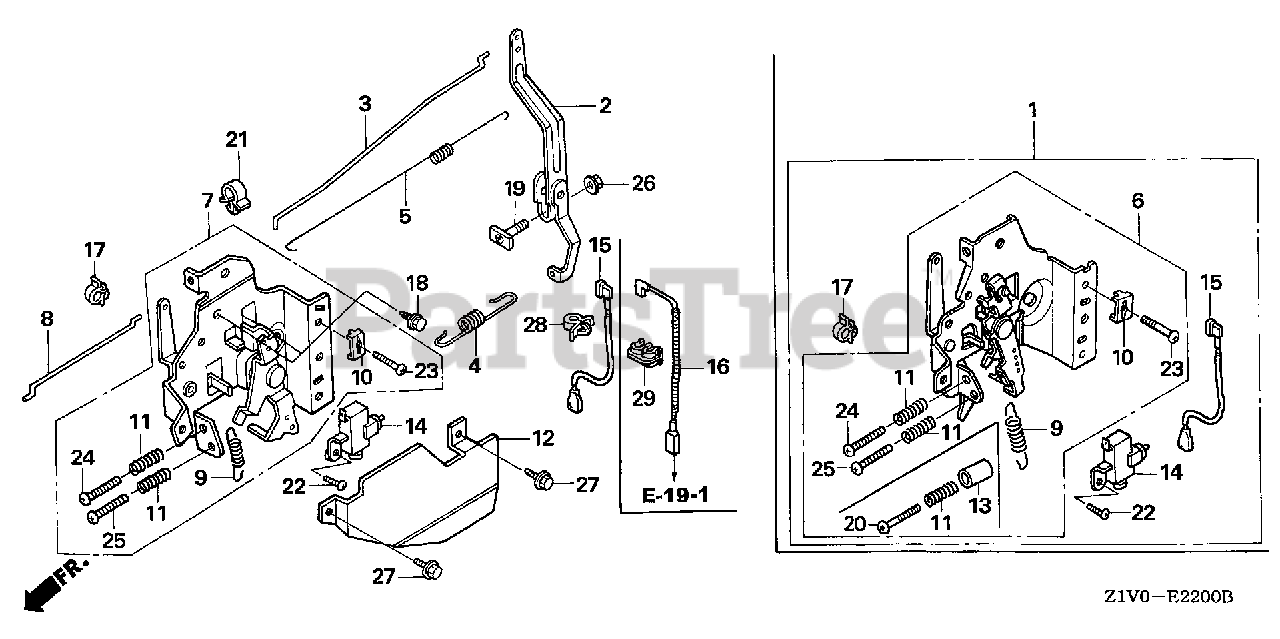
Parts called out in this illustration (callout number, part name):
2	ARM, GOVERNOR
3	ROD, GOVERNOR
4	SPRING, GOVERNOR
5	SPRING, THROTTLE RETURN
7	CONTROL ASSY.
8	ROD, CHOKE
9	SPRING, LEVER
10	HOLDER, CABLE
11	SPRING, CONTROL ADJUSTING
12	PROTECTOR, CONTROL
14	SWITCH ASSY., ENGINE STOP
15	WIRE, STOP SWITCH
17	HOLDER, STOP SWITCH WIRE
18	BOLT, FLANGE (6X12) (CT200)
19	BOLT, GOVERNOR ARM
21	CLIP, WIRE HARNESS
22	SCREW, PAN (4X8)
23	SCREW, PAN (5X16)
24	SCREW, PAN (5X20)
25	SCREW, PAN (5X28)
26	NUT, FLANGE (6MM)
27	BOLT, FLANGE (6X10)
28	CLAMP, BRAKE PIPE (GRAY)
